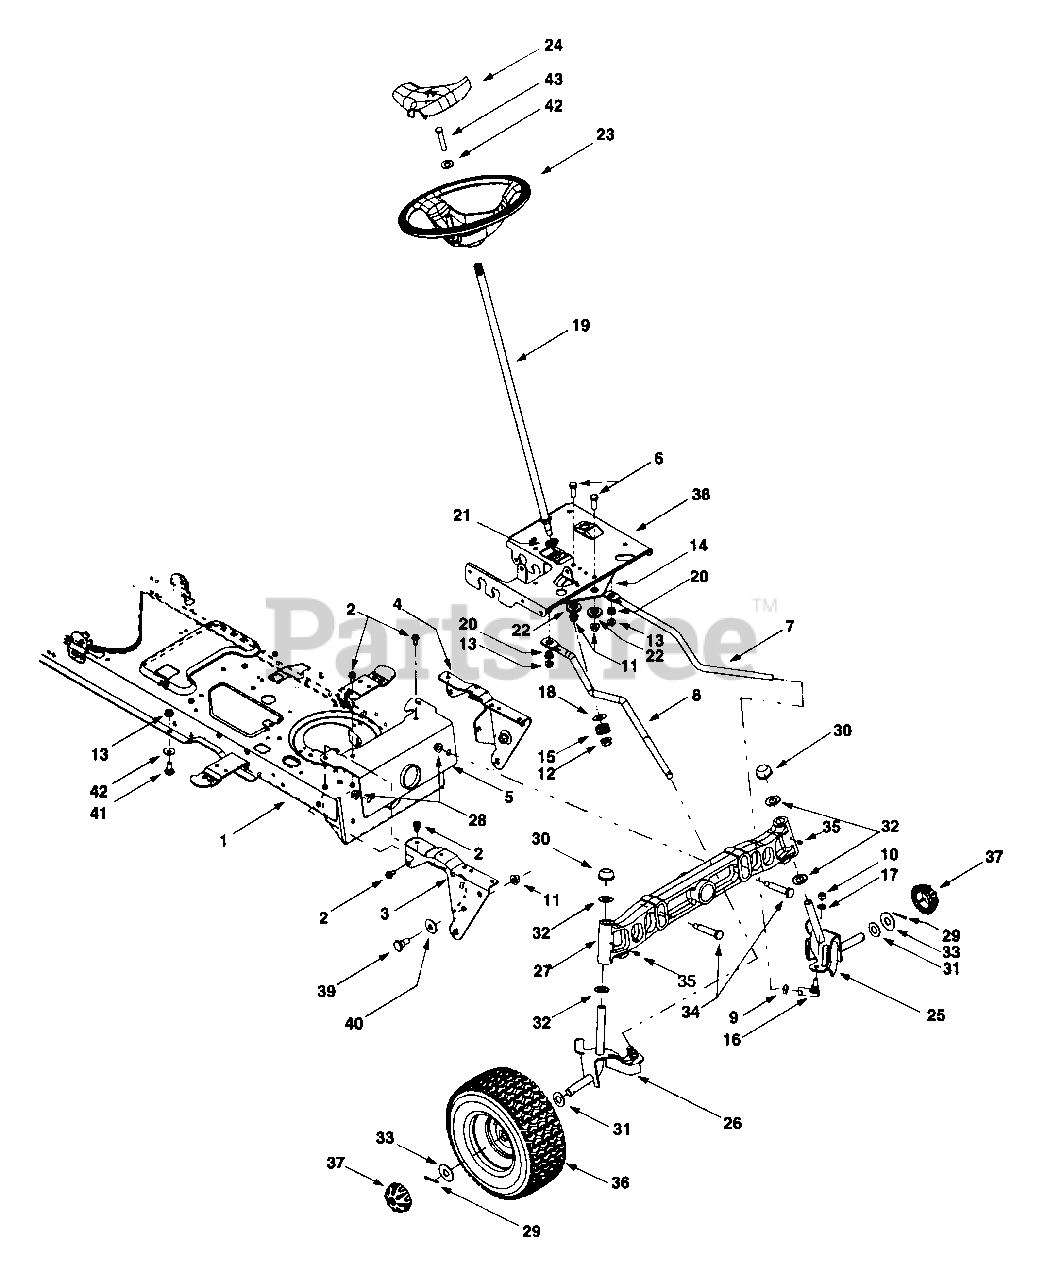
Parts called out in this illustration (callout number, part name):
6	Hex Cap Screw, 3/8-16 x 1 (Grade 5)
7	LH Drag Link
8	RH Drag Link
9	Jam Nut, 7/16-20 (Grade 2)
10	Hex Nut, 3/8-24 (Grade 2)
11	Flange Lock Nut, 3/8-16
12	Flange Lock Nut, 7/16-20
13	Flange Lock Nut, 5/16-18
14	Steering Gear, 11/90 Ratio
15	Steering Pinion Gear
16	Ball Joint, 7/16-20
17	Lock Washer, 3/8
18	Flat Washer, .51 x 1.12 x .06
19	Steering Shaft, .625 OD x 24.4
20	Plastic Bushing, .38 ID
21	Hex Flange Bearing, 5/8
22	Shoulder Spacer, .38 ID
23	Soft Touch Steering Wheel
24	Steering Wheel Insert
25	LH Axle Assembly, .750 Diameter
26	RH Axle Assembly, .750 Diameter
27	Cast Iron Pivot Bar
28	Flange Lock Nut, 3/8-16
29	Cotter Pin
30	Push Cap, .750
31	Flat Washer, .64 x 1.0 x .12
32	Flat Washer, .78 x 1.59 x .06
33	Flat Washer, .635 x 1.589 x .06
34	Shoulder Screw, .5 x 2.2, 3/8-16
35	Lube Fitting, 3/16
36	Wheel Assembly Complete, 16 x 6.5 x 8
37	Hub Cap
39	Shoulder Screw, 3/8-16
40	Bell Washer, .39 x 1.13 x .062
41	Shoulder Screw, .435 x .178, 5/16 x .56
42	Bell Washer, .34 x .872
43	Hex Bolt, 5/16-18 X 1
